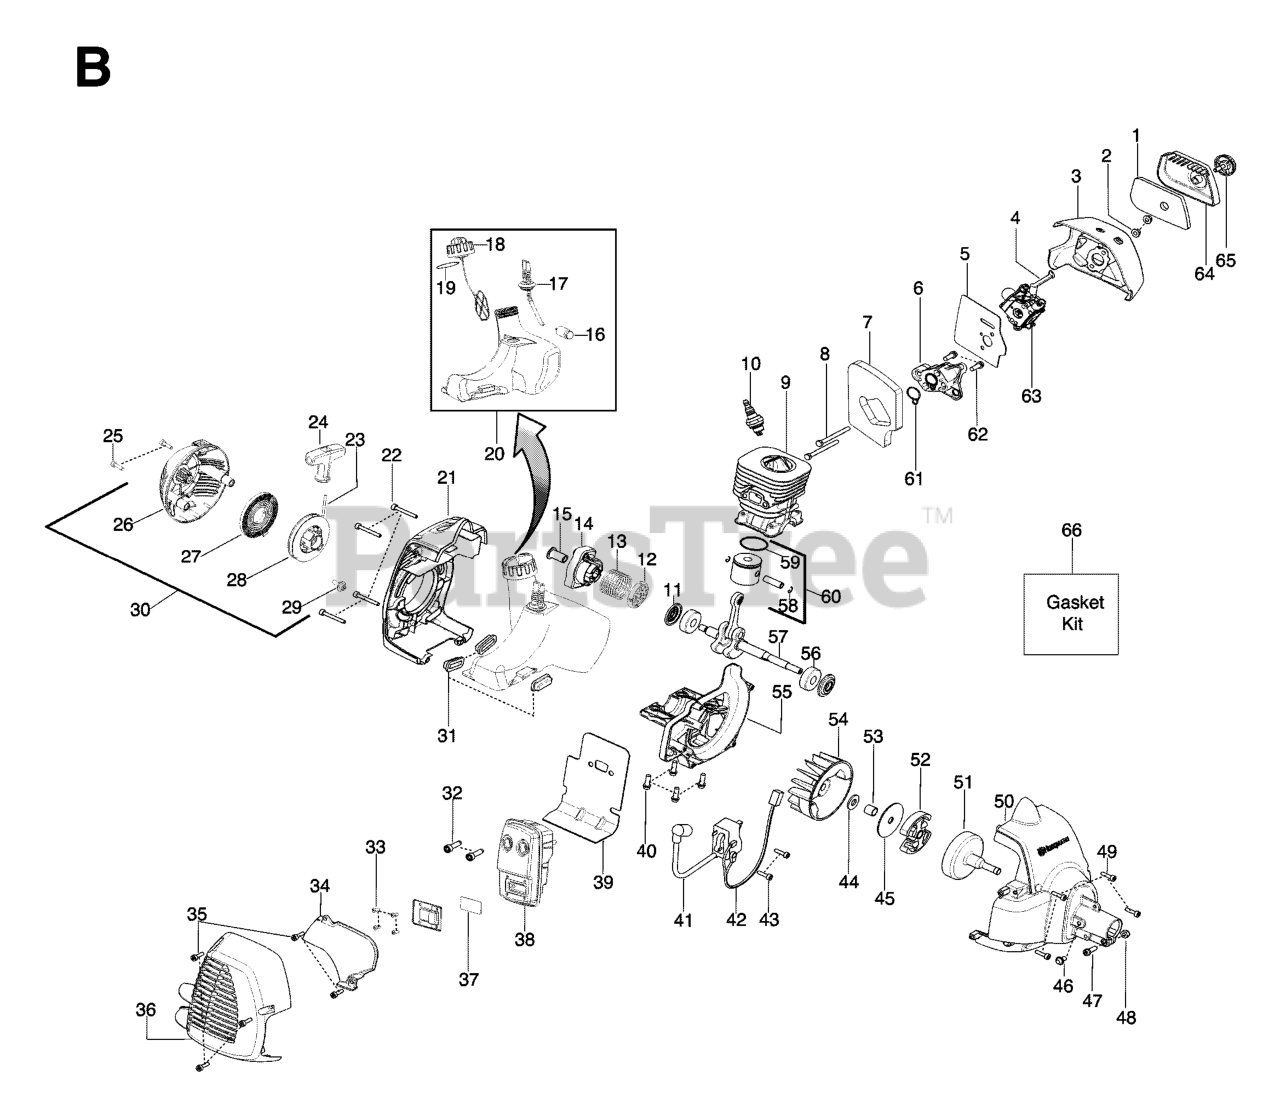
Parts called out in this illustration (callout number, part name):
1	FILTER AIRBOX
3	AIRBOX
4	CHOKE LEVER
5	KIT GASKET CARB
6	CARB ADAPTOR
7	KIT GASKET 28CC TRIMMER
8	BOLT CARB ADAPTOR
9	CYLINDER
10	Plug - Spark (RCJ-8Y)
11	KIT SEAL CRANKSHAFT
12	WASHER STARTER
13	SPRING STARTER CUP
14	ASSY STARTER CUP
15	COUPLING STARTER
16	FUEL PICK-UP ASSY
17	KIT FUEL LINE
18	ASSY-CAP W/RETAINER
19	O RING NITRILE
20	ASSY FUEL TANK
21	REAR SHROUD
24	STARTER HANDLE GRAY
25	SCREW M5-0.8X30MM
26	STARTER HOUSING
27	%KIT STARTER SPRING
28	KIT STARTER PULLEY
30	STARTER HOUSING ASSY
31	ISOLATOR FUEL TANK
32	BOLT MUFFLER
33	SCREW-10-16 X 1/2 HI-LO
34	SHIELD HEAT
35	SCREW M4 X 1.75 PT 16MM
36	MUFFLER GUARD
37	KIT SPARK ARRESTOR SCREEN
38	ASSY MUFFLER
39	GASKET PAPER METAL
40	SCREW-M5-0.8 X 25MM(TAP)
41	IGNITION MODULE MBU-7
42	ASSY MODULE LEAD WIRE
43	SCREW M4 X .70 TT 16MM
45	WASHER-CLUTCH
48	NUT HEX LOCK 10-24
49	SCREW M4 X .70 TT 16MM
50	FAN HSG ASSY
51	ASSY-CLUTCH DRUM
52	%KIT CLUTCH ASSY
53	SPACER FLYWHEEL
55	CRANKCASE CASTING
56	BEARING RADIAL BALL (6201)
57	KIT CRANKSHAFT ASSY
58	WRIST PIN RET.
59	RING PISTON
60	KIT PISTON 28CC TRIMMER
61	KIT GASKET 28CC TRIMMER
62	SCREW-M5-0.8 X 25MM(TAP)
63	KIT CARBURETOR
64	KIT GASKET 28CC TRIMMER
65	COVER-AIR BOX
66	KNOB ASSY AIRBOX COVER
67	KIT GASKET 28CC TRIMMER
